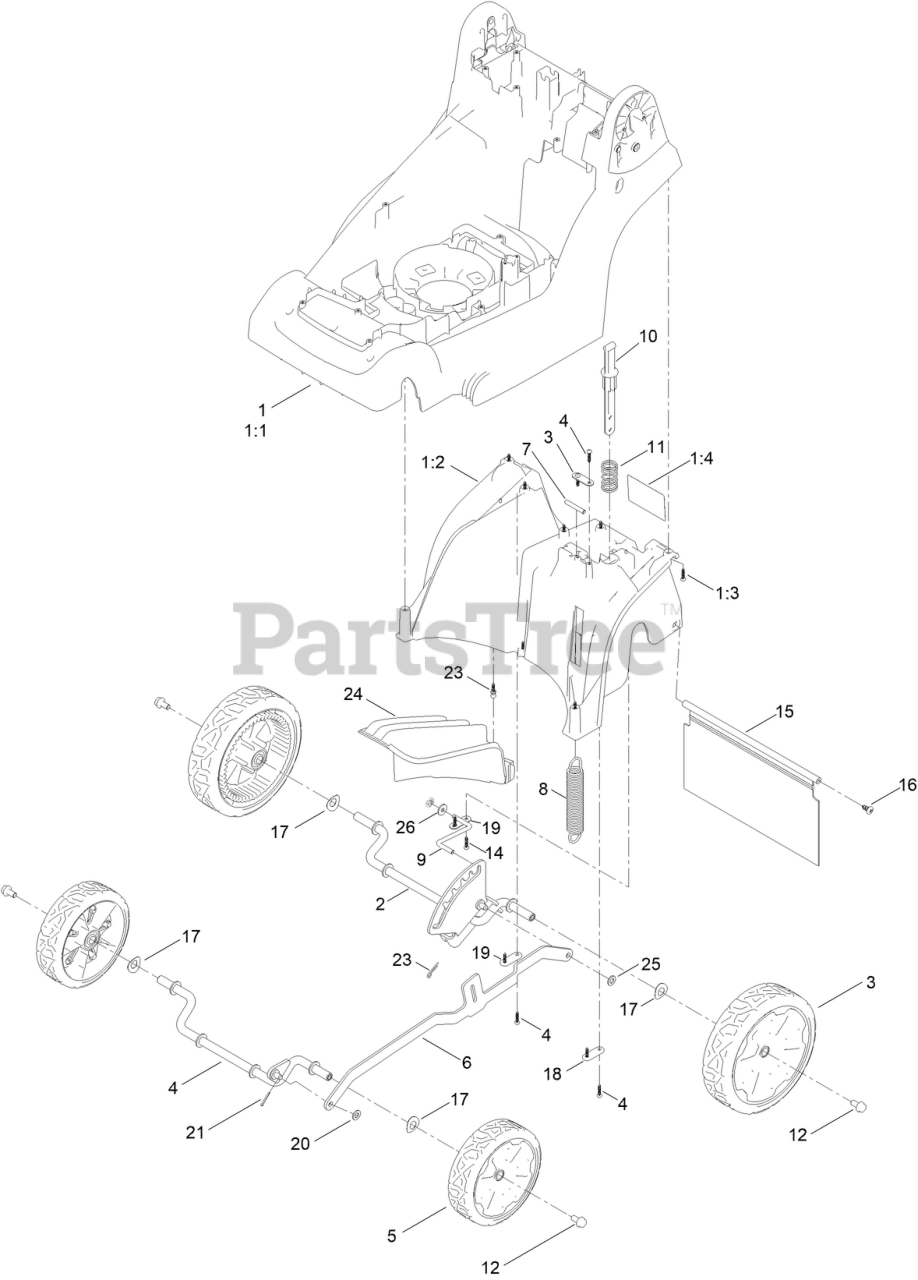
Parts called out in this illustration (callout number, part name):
1	DECK, GLUED (36)
1:1	DECK-36CM
1:2	36CM 4 WHEEL REAR CHASSIS MOULDING
1:3	SCREW, T20
1:4	DECAL - SAFETY
2	REAR AXLE FRAME, ASSY, WHEEL
3	WHEEL-REAR ASSEMBLY
4	FRONT AXLE, ASSEMBLY
5	WHEEL-TORO FRONT ASSEMBLY
6	CON-ROD, 4 WHEEL
7	BAR, SPRING MOUNT
8	HOC SPRING, 4 WHEEL
9	HOC WIRE
10	HOC BUTTON PLUNGER
11	SPRING, HOC BUTTON
12	BOLT, M8 X 1.25, 16MM
15	SHIELD-TRAILING, 36CM
16	SCREW-PTH
17	WAVE WASHER, FRONT WHEELS
18	AXLE PLATE
19	AXLE PLATE, SMALL
20	WASHER-PLAIN
21	COTTER PIN
23	PIN, RETAINING, MULCH PLUG
24	MULCH PLUG
25	WASHER
26	WASHER
